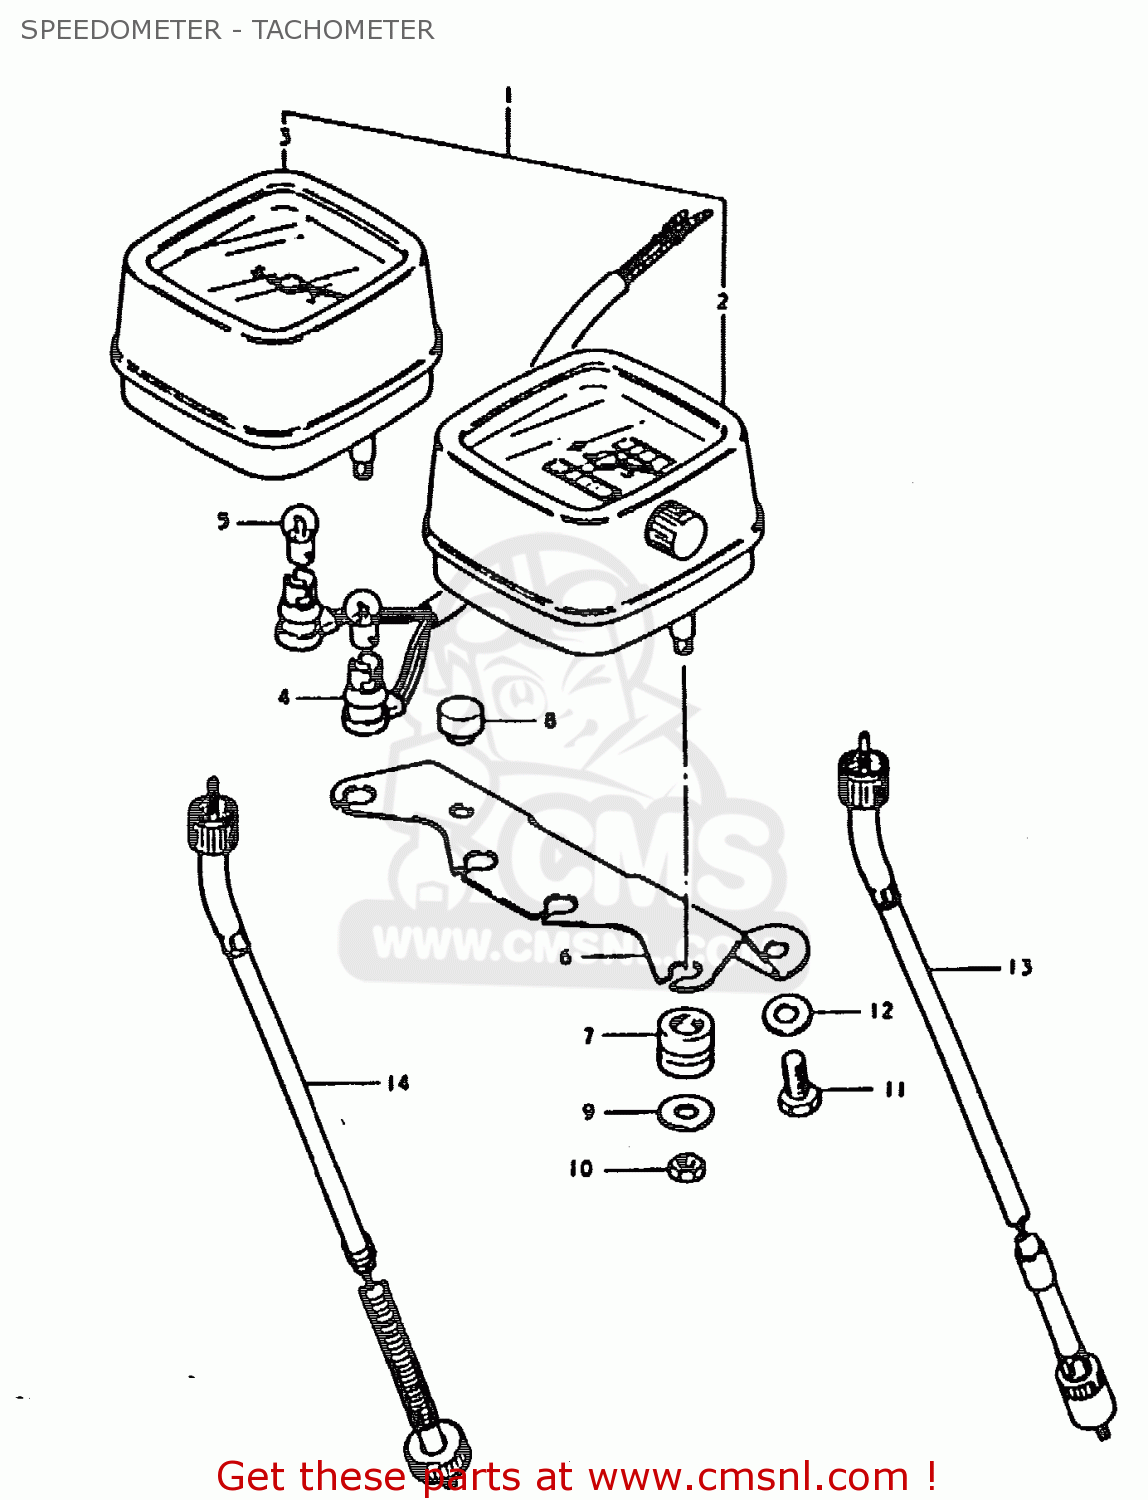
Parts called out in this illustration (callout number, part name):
1	SPEEDOMETER & TACHOMETER (KILO SCALE)
2	SPEEDOMETER (KILO)
3	TACHOMETER
4	SOCKET
5	BULB(6V1.7W,STANLEY,A61A)
6	BRACKET
7	CUSHION
8	CUSHION,METER
9	WASHER,METER
10	NUT
11	BOLT, UPPER
12	WASHER
13	CABLE ASSEMBLY,SPEEDOMETER
14	CABLE ASSY, TACHOMETER
